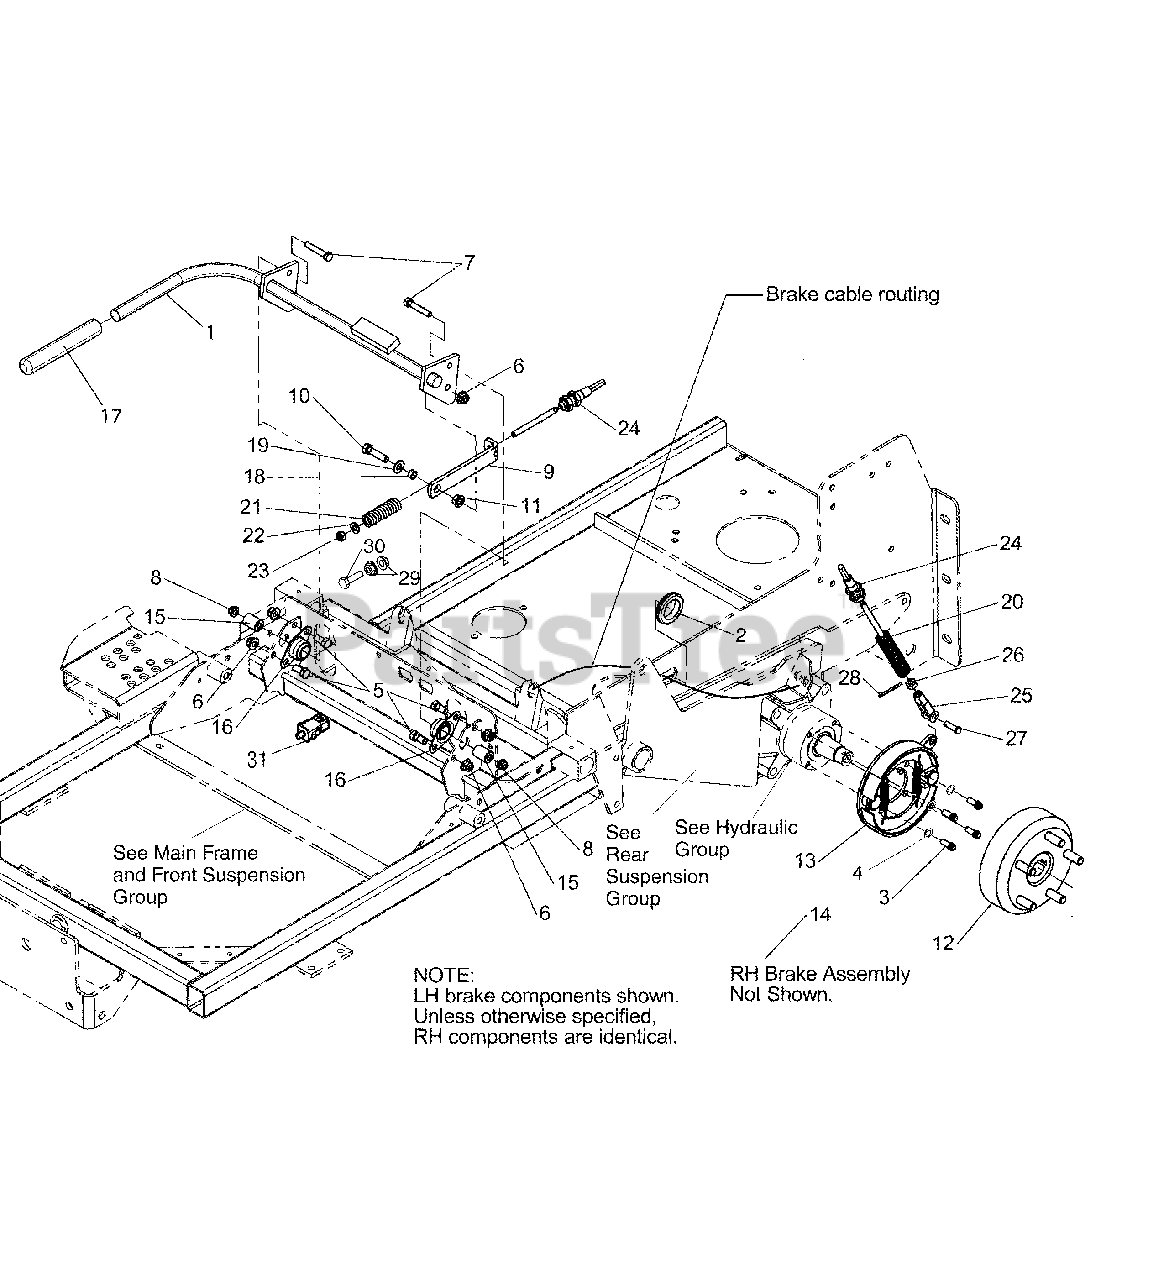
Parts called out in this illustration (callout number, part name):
1	WELD, BRAKE SHAFT - BLK
2	GROMMET, 1-1/4
3	BOLT, 5/16-18 X 3/4 12PT FLANGE - PATCH
4	WASHER, 5/16 LOCK YZ
5	BOLT, 3/8-16 X 3/4 GD5 YZ
6	NUT, 3/8-16 HEX NYLOCK FLANGE
7	BOLT, 5/16-18 X 1-3/4 GD5 YZ
8	NUT, 5/16-18 HEX NYLOCK FLANGE
9	LINK, BRAKE LOCK - BLK
10	BOLT, 3/8-16 X 1-1/2 GD5 YZ
11	NUT, 3/8-16 HEX SERRATED FLANGE
12	BRAKE DRUM, 6", 5 BOLT, KNOTT
12	DRUM,1-1/4TAPER,5 BOLT
13	BRAKE SHOE ASM, LH, KNOTT
13	BRAKE ASSEMBLY, LH
15	SPACER, .32 X .75 X 1.06
16	BEARING, BRONZE FLANGE, 3/4
17	GRIP, FOAM, 3/4 ID X 6 X .187
18	SPACER, .38 X .50 X .27
19	WASHER, 3/8 SAE
20	SPRING, COMPRESSION
21	SPRING-COMP, .75 X .162 X 2.5
22	WASHER, 5/16" SAE
23	NUT, 5/16-24 HEX NYLON LOCK
24	CABLE, PARKING BRAKE IS2000
25	CLEVIS, 5/16-24, STEEL, CLEAR ZINC
26	NUT, 5/16-24 HEX
27	PIN, CLEVIS, 5/16 X 1 YZ
28	PIN, HAIR, .0585 X 1-1/8, 1/4 EYE, YZ
29	NUT, 5/16-18 HEX SERRATED FLANGE (LARGE)
30	BOLT, 5/16-18 X 1-1/4 GD5 YZ
31	SWITCH, DP NO/NC SNAP-IN
